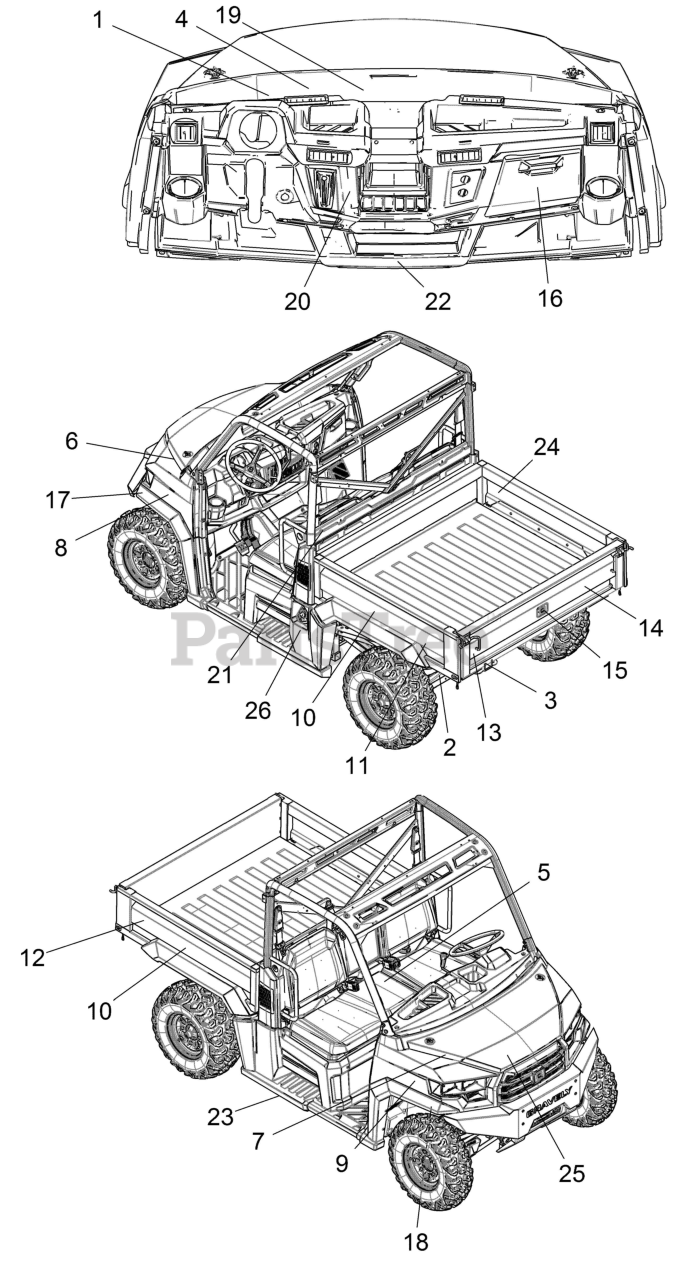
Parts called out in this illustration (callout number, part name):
1	DECAL, AGE WARNING 16
2	DECAL, REFLECTOR RED
3	DECAL-WARNING,TRAILER LOAD
4	LABEL, OPEI COMPLIANCE
5	DECAL, WARNING, PULLEY
6	DECAL, HOOD TOP DIESEL LH
7	DECAL, HOOD TOP DIESEL RH
8	DECAL, HOOD SIDE ATLSJSV, LH
9	DECAL, HOOD SIDE ATLSJSV, RH
10	DECAL, BOX SIDE GRAVELY
11	DECAL, BOX SIDE 3000 LH
12	DECAL, BOX SIDE 3000 RH
13	DECAL, TAILGATE ATLSJSV, LH
14	DECAL, TAILGATE AWD RH
15	DECAL, TAILGATE GRAVELY CENTER
16	DECAL, GLOVEBOX COVER
17	DECAL, REFLECTOR AMBER LH
18	DECAL, REFLECTOR AMBER RH
19	DECAL, WARNING DISC GRAVELY
20	DECAL, CAUTION SHIFT/BRAKE
21	DECAL, ROPS GRAVELY 3000
22	DECAL,WARNING PASS/TIRE PRESS
23	DECAL NOT A STEP
24	DECAL, WARN, NEVER CARRY FUEL
25	DECAL-COOLANT
26	DECAL, WARN FUEL TRANSPORT
